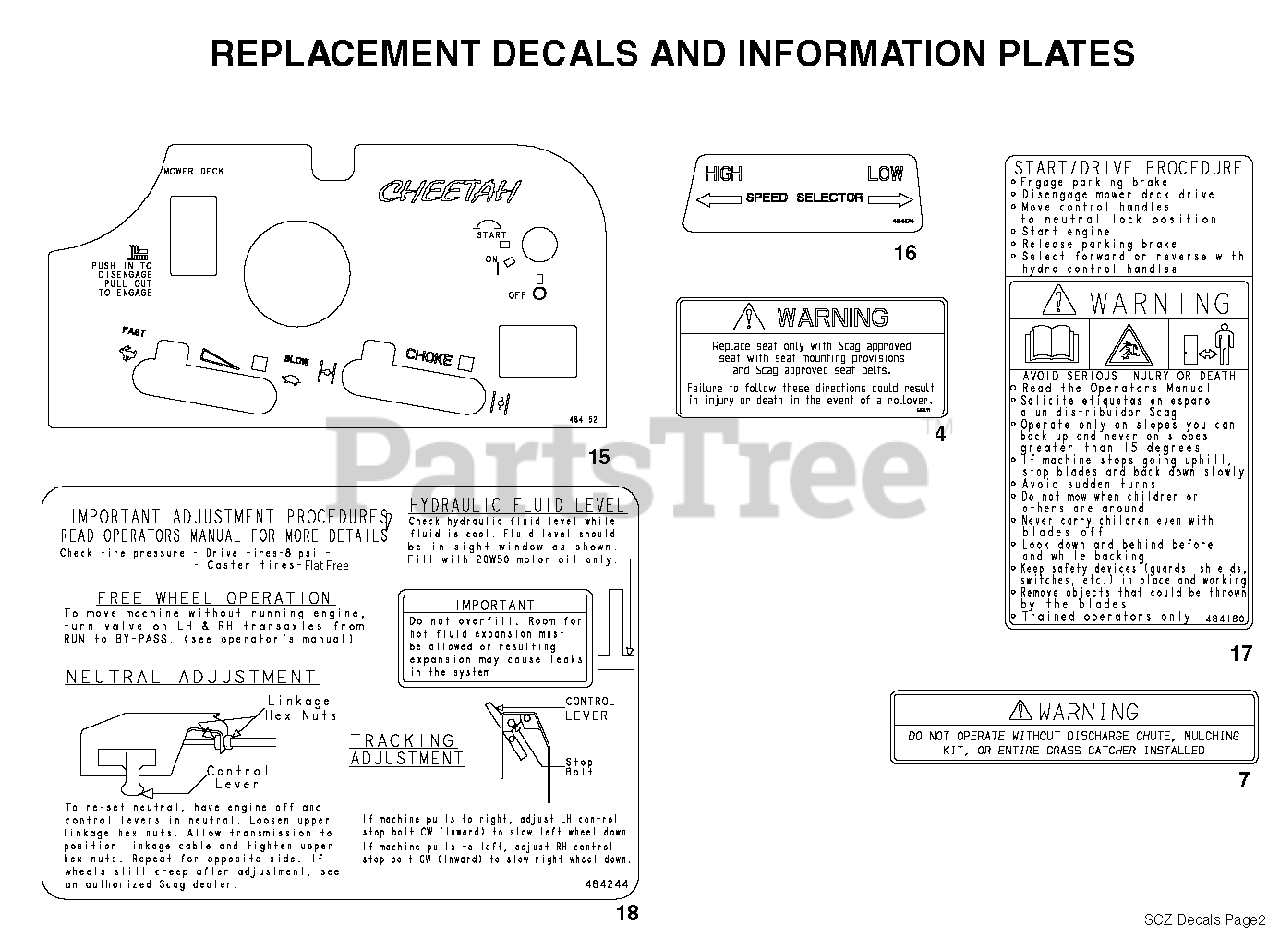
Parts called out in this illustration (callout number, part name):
4	Decal, Seat Replacement
7	Decal, Warning
15	Decal, Instrument Panel - SCZ
16	Decal, Speed Control
17	Decal, Start / Drive
18	Decal, Adjustments - SCZ
